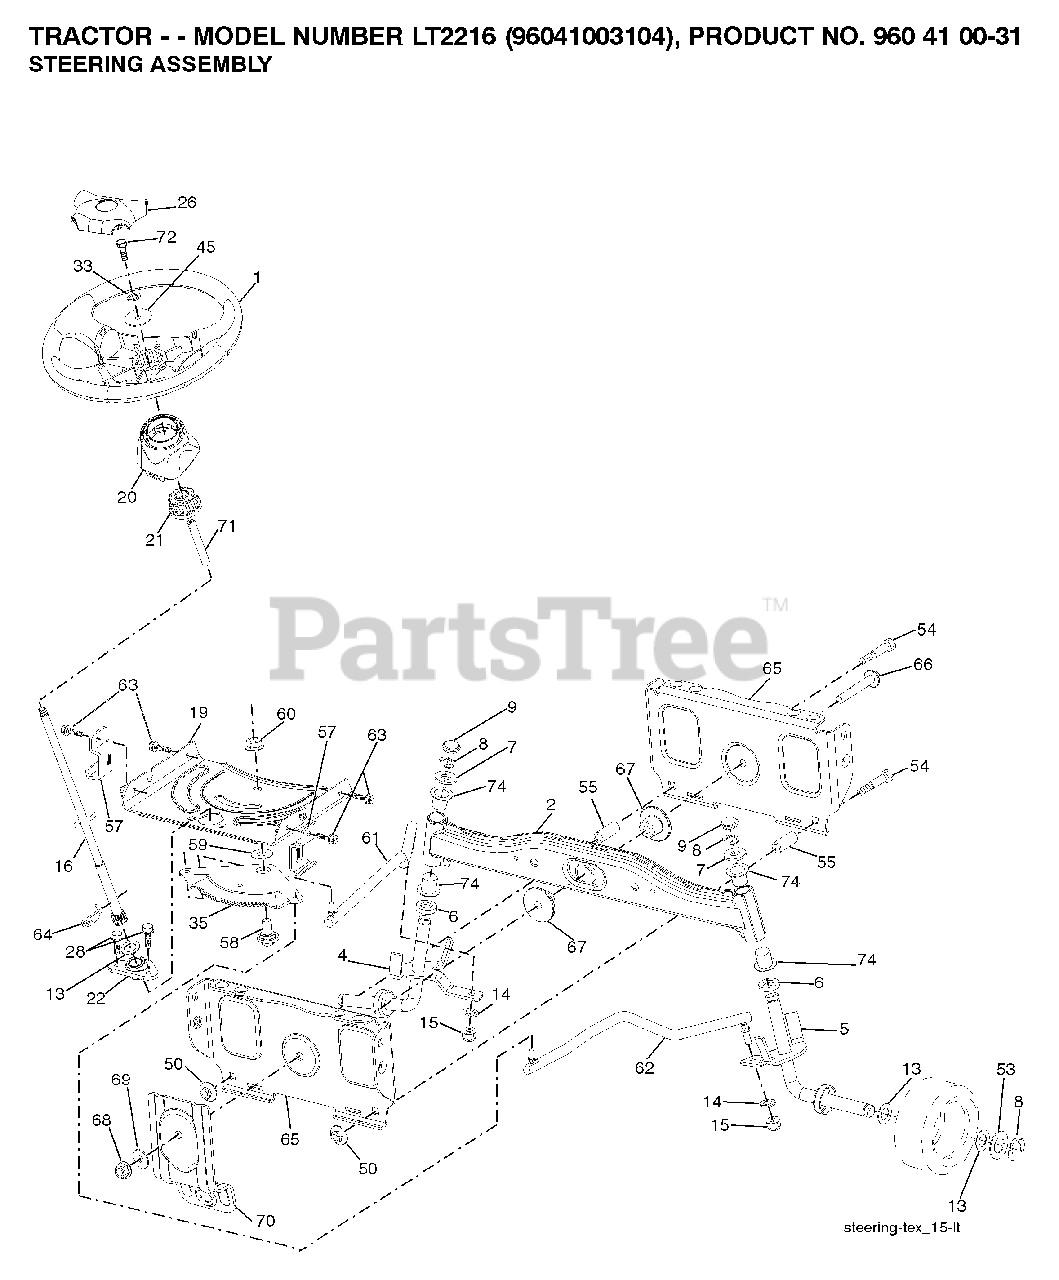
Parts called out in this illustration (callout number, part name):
2	AXLE.HALF.ASM.WELDED
4	SPINDLE.WELDED.LH.15"TEX
5	SPINDLE.WELDED.RH.15"T
8	RING CLIP
9	CAP.SPINDLE
14	WASHER, LOCK 3/8
15	NUT CROWNLOCK 3/8-24
16	SHAFT STEERING
19	PLATE.STEER.DDL.NLT/NG
20	BOOT STEERING BLACK
21	ADAPTER, WHEEL STNG..
22	BUSHING.ASM.STEERING.A
26	INSERT.CAP.STRG.WH.BLACK
28	SCREW, 3/8-16X3/4
33	LOCKWASHER
35	GEAR.SECTOR.PLATE.DDL.
45	WASHER.11/32
50	NUT LOCK FLG 3/8-16 UNC
53	WASHER.HARDENED
55	SPACER.BRACE.AXLE
57	BRACKET.UPSTOP.TEX
58	BOLT.SHOULDER.SECTOR.P
59	WASHER.THURST.SECTOR.S
60	NUT FLANGE LOCK 5/8-11
61	DRAGLINK.LH.BALLSTUD.D
62	DRAGLINK.RH.BALLSTUD.D
63	SCREW
64	RETAINER.CLIP.SPRING.S
65	BRACE.AXLE.FRONT.NLT/N
66	BOLT HEX FGHD 7/16-14 X 3 SERR
67	BUSHING.PM.FRONT AXLE
68	NUT.LOCK.FLANGE.7/16
69	WASHER.1.5X.505X.118
70	BRKT.DECK.SUSPENSION.F
71	SHAFT EXTENSION STEERING
72	BOLT YT
74	BRNG T
